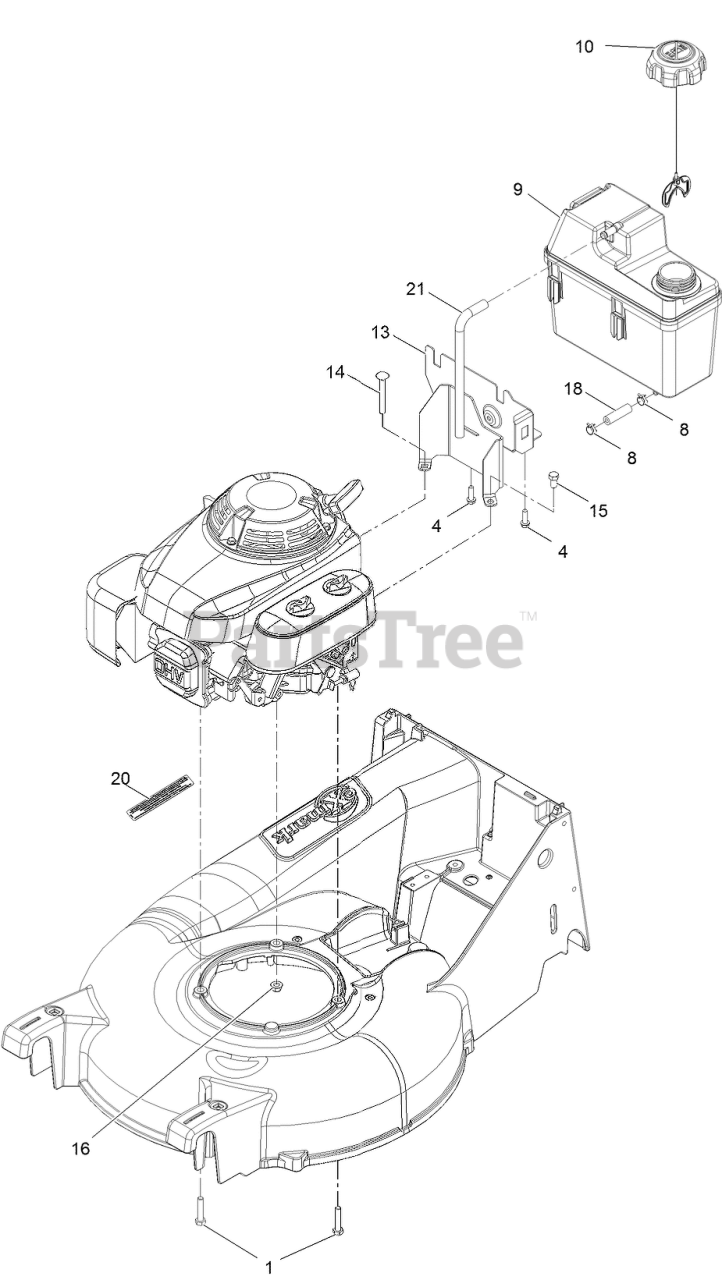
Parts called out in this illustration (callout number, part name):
1	SCREW-HH
4	SCREW-HWH
8	CLAMP-HOSE
9	TANK-FUEL
10	CAP-FUEL
13	BRACKET ASM
14	SCREW-CARR
15	SCREW-HH
16	NUT-HF, NI
18	HOSE-FUEL
20	DECAL-ARRESTOR, SPARK
21	HOSE-VENT, CANISTER
